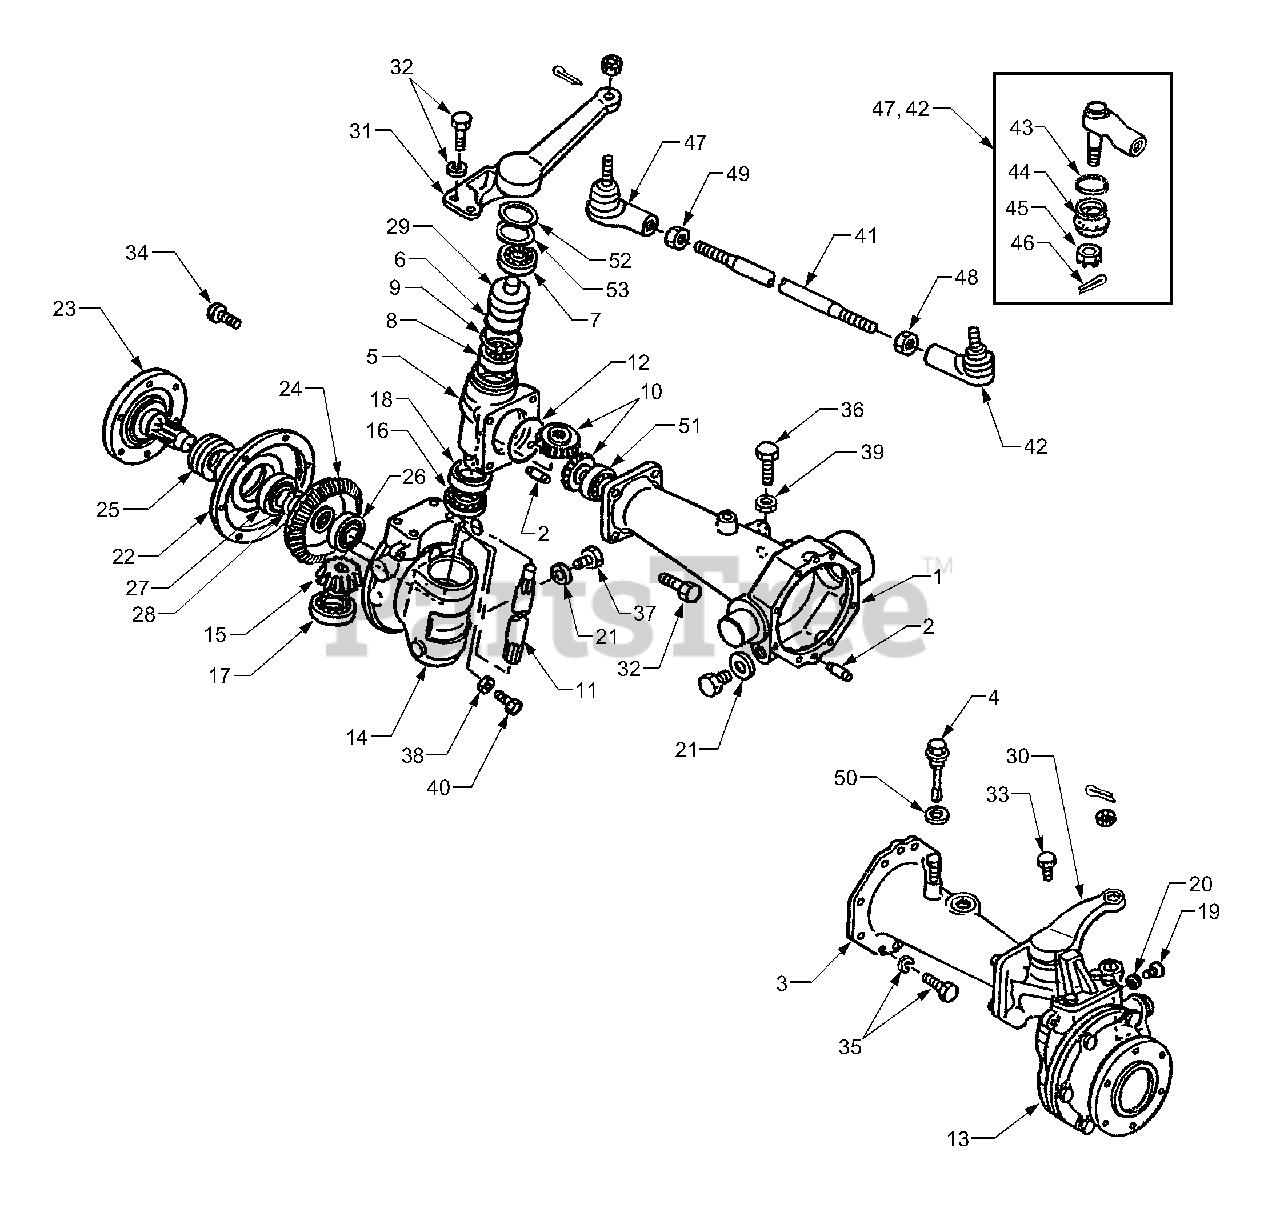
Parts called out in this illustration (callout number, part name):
1	Housing Assembly, Axle
3	Housing, Axle LH
4	Gauge, Oil Level
5	Housing Assembly, Pinion Gear
7	Bearing, Ball
8	Bearing, Ball
10	Gear, Final Pinion Idler
11	Shaft, Idler Drive
13	Housing, Final Drive LH
14	Housing, Final Drive RH
15	Gear, Final Drive Pinion
16	Bearing, Tapered
17	Bearing, Ball
20	Washer, Seal
21	Washer, Seal
22	Housing, Final Drive
23	Wheel Hub/Shaft
24	Gear, Final Drive
25	Seal, Oil, 35mm x 55mm x 15mm
26	Bearing, Ball
27	Bearing, Ball
30	Arm, Steering LH
31	Arm, Steering RH
32	Bolt, M10 x 25
33	Bolt, M10 x 30
34	Bolt, M8 x 20
35	Bolt, M8 x 25
36	Bolt, M10 x 35
37	Bolt, M12 x 12
40	Bolt, M8 x 25
42	Tie Rod End, LH
43	Spring, Dust Cover
45	Nut, Castle, M12 x 1.25
47	Tie Rod End, RH
48	Nut, Jam, LH Thrd
49	Nut, Jam, M14 RH Thrd
50	Washer, Seal
51	Bearing, Ball
